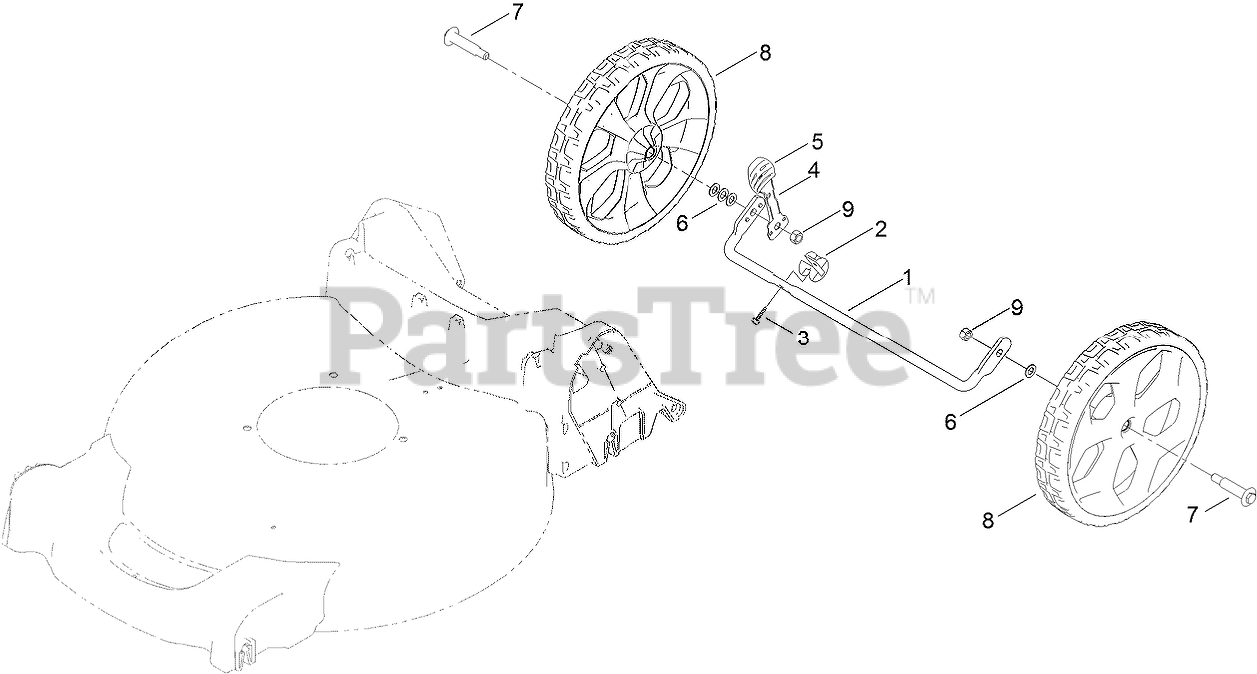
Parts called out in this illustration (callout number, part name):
1	AXLE-REAR
2	STOP-AXLE
3	SCREW-HWH
4	ARM-SPRING, REAR
5	KNOB-LEVER, HOC
6	WASHER
7	BOLT-SHOULDER
8	11 INCH WHEEL ASM
9	LOCKNUT
